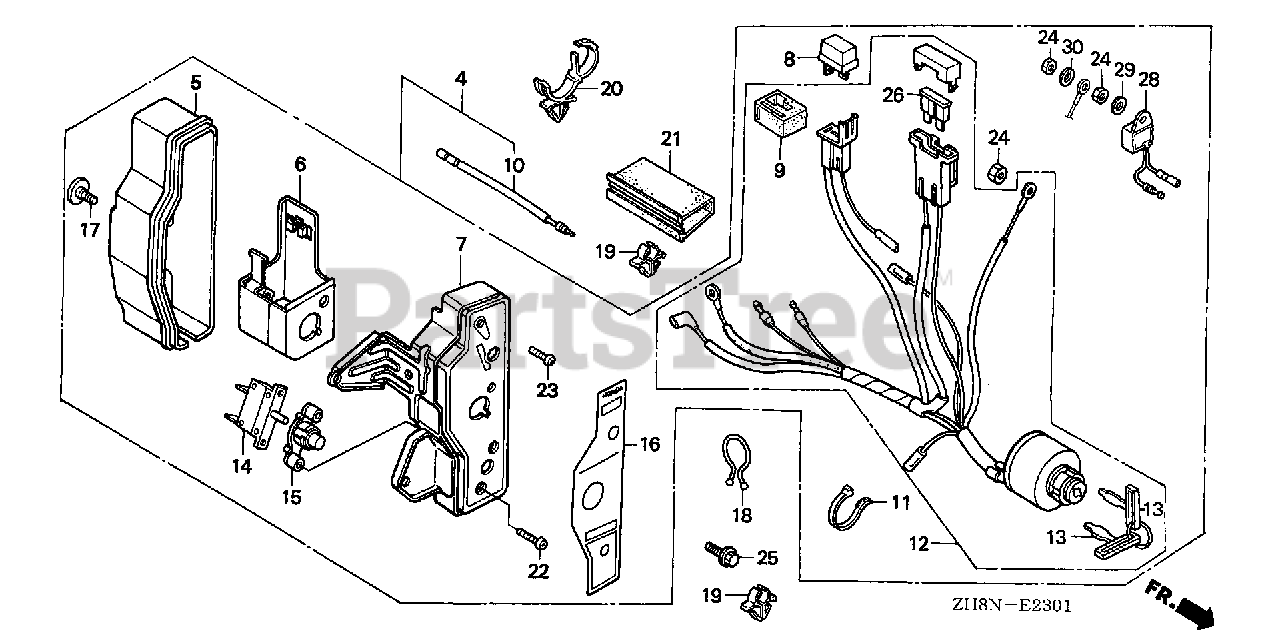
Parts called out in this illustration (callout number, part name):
4	BOX ASSY., CONTROL *R8* (EXTERNAL-ALERT) (BRIGHT RED)
5	CASE, CONTROL
6	BRACKET, CASE MOUNTING
7	PANEL, CONTROL *R8* (BRIGHT RED)
8	RECTIFIER ASSY., SILICON (STANLEY)
9	SUSPENSION, CONNECTOR
10	SUB-HARNESS
11	BAND
12	SWITCH ASSY., COMBINATION
13	KEY
14	PROTECTOR, CIRCUIT (1.0A)
15	LENS ASSY., PROTECTOR
16	PANEL, CONTROL BOX (EXTERNAL)
17	SCREW, SPECIAL (6X12)
18	CLIP, PURSE LOCK
19	CLIP, CORD
20	STRAP, WIRE HARNESS (25MM) (BLACK)
21	TUBE, FASTENER (30)
22	SCREW, PAN (3X12)
23	SCREW, PAN (4X12)
24	NUT, HEX. (4MM)
25	BOLT, FLANGE (6X10)
26	FUSE, BLADE (5A)
28	ALERT UNIT, OIL
29	WASHER, PLAIN (4MM)
30	WASHER, SPRING (4MM)
